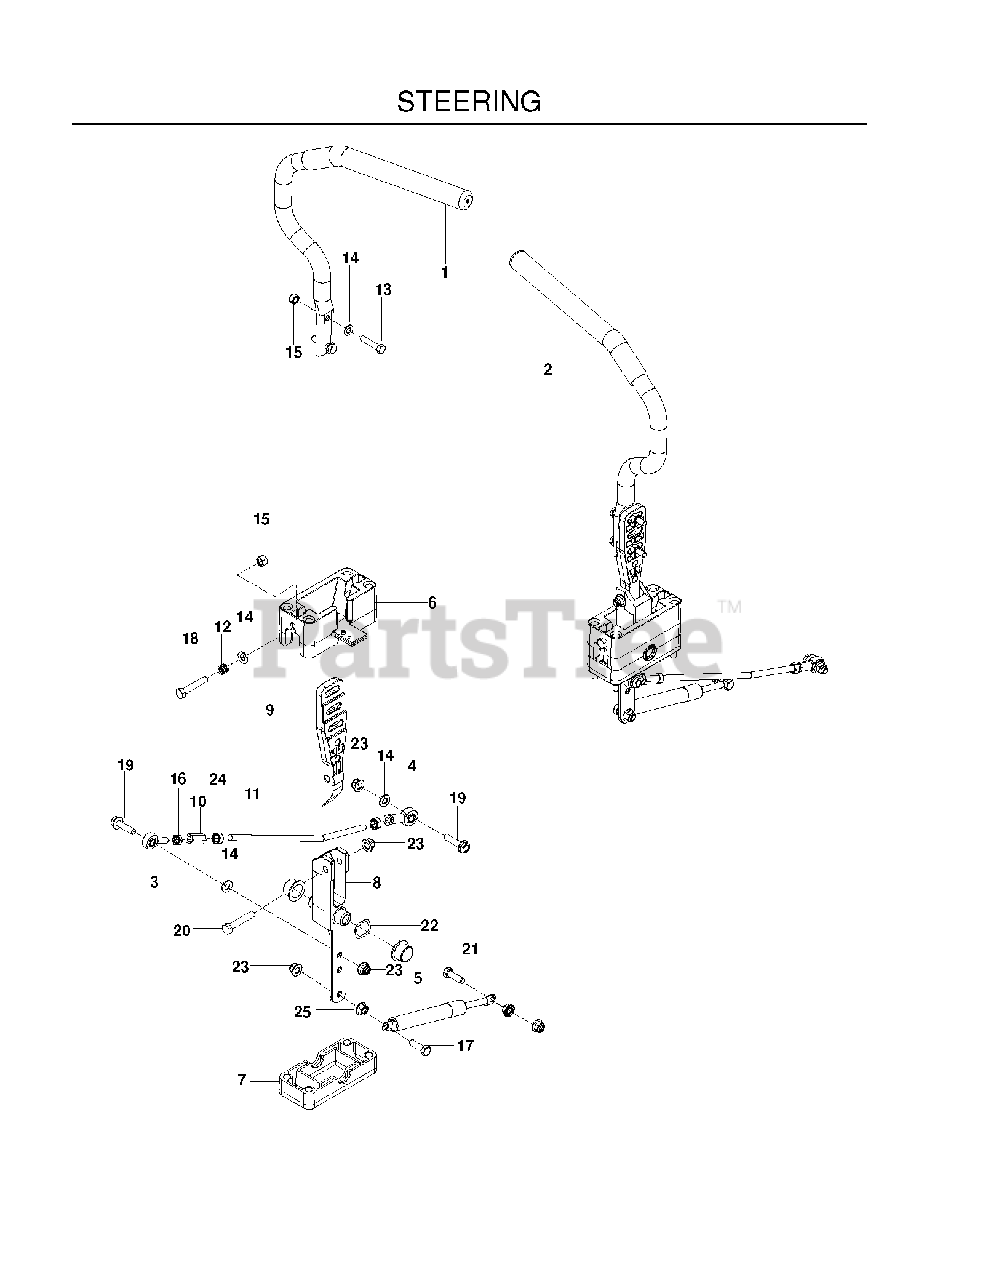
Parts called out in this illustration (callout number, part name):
1	LEVER DRIVE W/GRIP RT
2	LEVER, DRIVE W/GRIP LT
3	ROD END LH
4	RH ROD END
5	DAMPENER
6	BLOCK, UPPER
7	BLOCK, LOWER
8	PIVOT SECTION, DRIVE CONTROL
9	MOUNT, DR CNTRL HANDLE
10	ROD END COUPLER
11	ROD, CONTROL
13	CAPSCREW 5/16 X 1/1/2 HEX HEAD
14	FLAT WASHER 5/16 SAE
15	NUT 5/16 NYLOC
16	NUT 5/16F LEFTHAND
17	HCS 5/16C X 1
18	HCS 5/16-18X1-3/4 TPBLT
19	HHFS 5/16-18 X 1.25 TPBLT GD 5
20	HCS 5/16C X 1 3/4
21	BEARING, FLANGE
22	WASHER, .825 X 1.087, WAVE
23	5/16-18 NYLOC FLANGE NUT
24	NUT 5/16F
25	NUT 5/16C WHIZ
